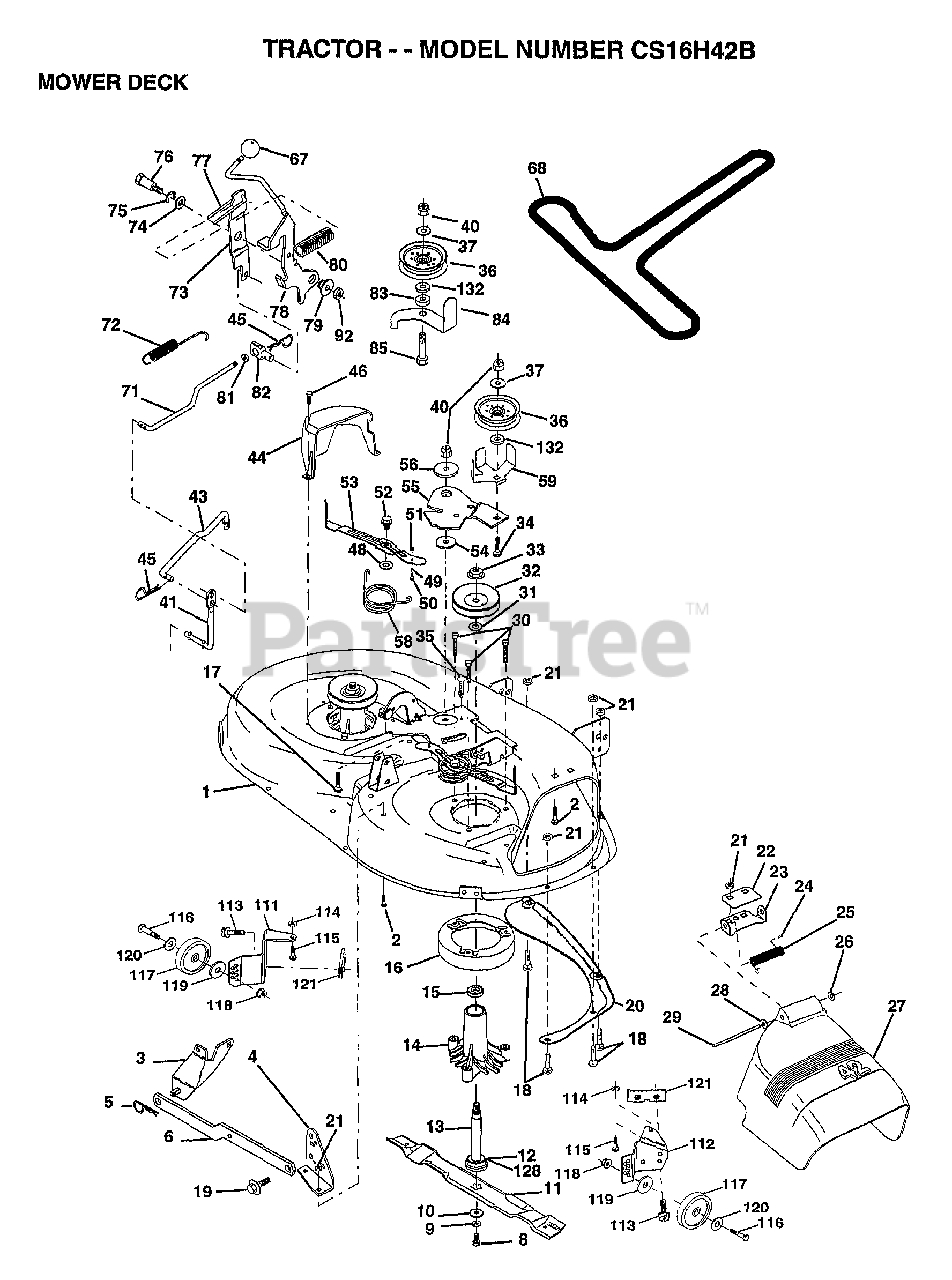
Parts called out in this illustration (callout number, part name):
1	DECK.WELD.42.
2	BOLT
3	BRKT ASM SWAY BAR
4	BRKT DECK SW BAR
8	BLADE BOLT
10	WASHER.HARD.BLADE
11	"BLADE.42"" HIPERF"
12	BEARING.BALL
14	HSG ASM MANDREL
15	BEARING
16	STRIPPER RND MWR
17	BOLT RDHD 3/8-16
18	BOLT
19	BOLT SHD 5/16-18
22	STIFFENER BRKT
23	DEFLECTOR BRKT
24	CAP-SLEEVE LT
25	SPRING TORSION
26	NUT PUSH M
27	DEFLECTOR.SHIELD
28	WASHER
29	HINGE ROD
30	"SCREW-THD ROLL,WA"
31	WASHER
32	PULLEY.MANDREL.42
34	BOLT
35	XMAS TREE FASTNER
36	FLAT IDLER PULLEY
37	WASHER
41	PIVOT ROD
43	ROD CLUTCH W/NIBS
44	GUARD MAND LH BLK
45	RETAINER M
46	SCREW.1/4-20X5/8
48	HARD SMALL WASHER
49	ROLLER ASM-CAM
50	SHOULDER BOLT
51	LOCKNUT
52	BOLT.SHLD.5/16-18
54	HARDENED WASHER
55	ARM-IDLER
56	SPACER RETAINER
58	SPRING TORSN BRAK
59	GUARD IDLER TUV
67	KNOB T(3/8 HOLE)
68	BELT.V.T-PATH
71	ROD CLUTCH 38/42
72	RETURN SPRING
73	CLUTCH ARM SECOND
74	WASHER
75	RING
76	SHOULDER BOLT
77	SPRING KEEPER
78	LEVER ASM-CLUTCH
79	BUSHING
80	SPRING.CLUTCH.MWR
81	TRUNION ADJ
82	NUT
83	WASHER
84	"KEEPER-BELT,FIXED"
85	BOLT RDHD 3/8-16
92	NUT
111	BRACKET.GWHL.LH.
112	BRACKET.GWHL.RH.
113	SCREW
116	BOLT M
117	WHEEL.GAGE.BLK.PL
118	LOCKNUT
119	WASHER
120	WASHER
121	BRACKET.EXTRD.GWL
128	WASHER.FELT.
132	WASHER GT
